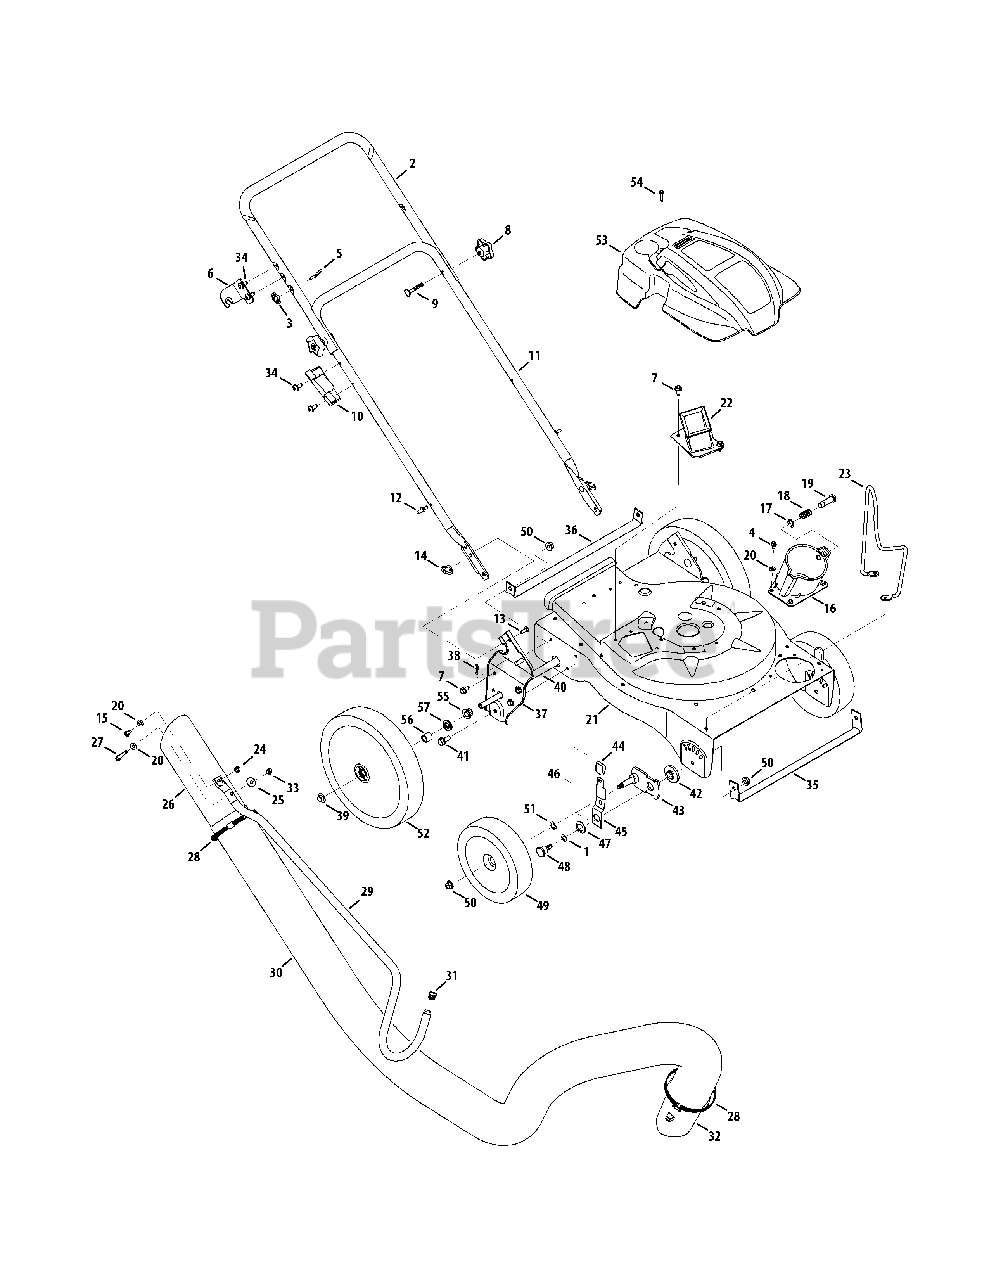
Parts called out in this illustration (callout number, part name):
1	Thrust Washer.375 ID x.70 OD
4	Screw, 1/4-20 x.500
6	Upper Handle Bracket
7	Hex Cap Screw 5/16-12 x.750
9	Carriage Bolt
10	Nozzle Handle Clip
13	Carriage Screw 1/4-20 x.75
14	Wing Nut 1/4-20
15	Hex Cap Screw 1/4-20 x.620
16	Hose Base Adapter Assembly
17	Ring.500 Dia
18	Compression Spring
19	Clevis Pin
20	Flat Washer.271 ID x.630 OD
21	Upper Flail Housing
22	Chipper Chute Assembly
23	Hose Cradle
24	Flange Lock Nut, 1/4-20
26	Hose Nozzle
27	Hex Cap Screw 1/4-20 x 2.625
28	Adjustment Clamp
30	Vacuum Hose
31	Handle Plug
32	Hose Adapter
33	Cap Lock Nut, 1/4-20
34	TT Screw, 5/16-18 x .750
35	Front Wheel Support Brace
36	Rear Wheel Support Brace
37	Handle Bracket Ass’y RH
37	Handle Brkt Ass’y LH
38	Cotter Pin
41	HHflg, 3/8-16 x .875
42	Height Adjustment Bearing
43	Pivot Arm Assembly
44	Height Adjustment Knob
45	Spring Lever
46	Height Lever Assembly
47	Bell Washer.760 ID x.25 OD
48	Shoulder Screw,.750 x.500
49	Front Wheel
50	Flange Lock Nut, 3/8-16
51	Washer, Wave, .531 x .781 x .013
52	Rear Wheel
53	Engine Shroud
54	Screw, #12-16 x 1.00
55	Brg. Flg, Hex
57	Washer, Flat, .508ID x 1.00 OD
